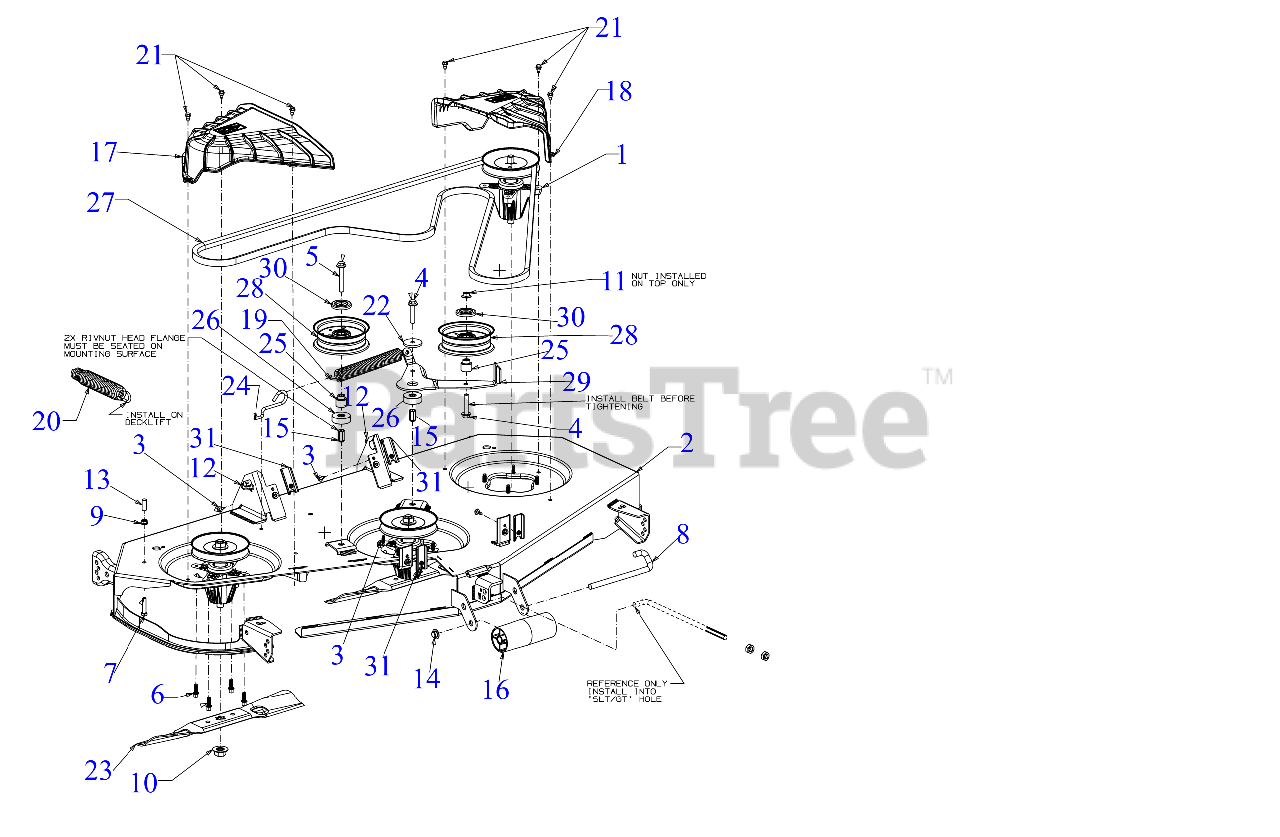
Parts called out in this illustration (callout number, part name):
1	SPINDLE ASSEMBLY
1	Cub Cadet 54" SPINDLE (06978 W/HDW)
2	54" DECK SHELL
3	SCREW M6-1 x .625
4	SCREW 3/8-16 x 2.0
5	SCREW 3/8-16 x 2.75 GR5
6	SCREW 5/16-18 x .875
7	SCREW 5/16-18 x 1.5 LG
8	ROLLER PIN 1/2 x 7.31
9	FLANGE LOCK NUT 5/16-18
11	FLANGE LOCK NUT
12	BOW TIE COTTER PIN
15	NUT RIVET 3/8-16
17	SPINDLE COVER (RH)
18	SPINDLE COVER (LH)
19	SPRING 1.25" DIA x 8.5" LONG
20	LIFT ASSIST SPRING (LARGE)
21	SHOULDER SCREW 1/4-20 x .50
22	SHOULDER SPACER
23	18.61" BLADE (2N1)
23	Cub Cadet 54" HI LIFT BLADE SET
23	Genuine Factory Parts 54" BLADE SET
23	54" 6 PT STAR LOW LIFT/SAND BLADE
23	Cub Cadet 54" LOWLIFT BLADE SET
23	Genuine Factory Parts 54" LOWLIFT BLADE SET
23	54" 6 PT STAR XTREME MULCH BLADE
23	Cub Cadet 54" XTREME BLADE SET
23	Genuine Factory Parts 54" XTREME MULCH BLADE SET
24	DECK SPRING HOOK
25	SHOULDER SPACER
26	SPACER .385ID x 1.75OD x .585THK
27	V-BELT B SEC x 139
27	Cub Cadet 54" DECK DRIVE BELT
27	Genuine Factory Parts 54" DECK BELT
28	IDLER PULLEY 4.50" DIA
29	IDLER PIVOT BRACKET
30	IDLER PULLEY CAP
